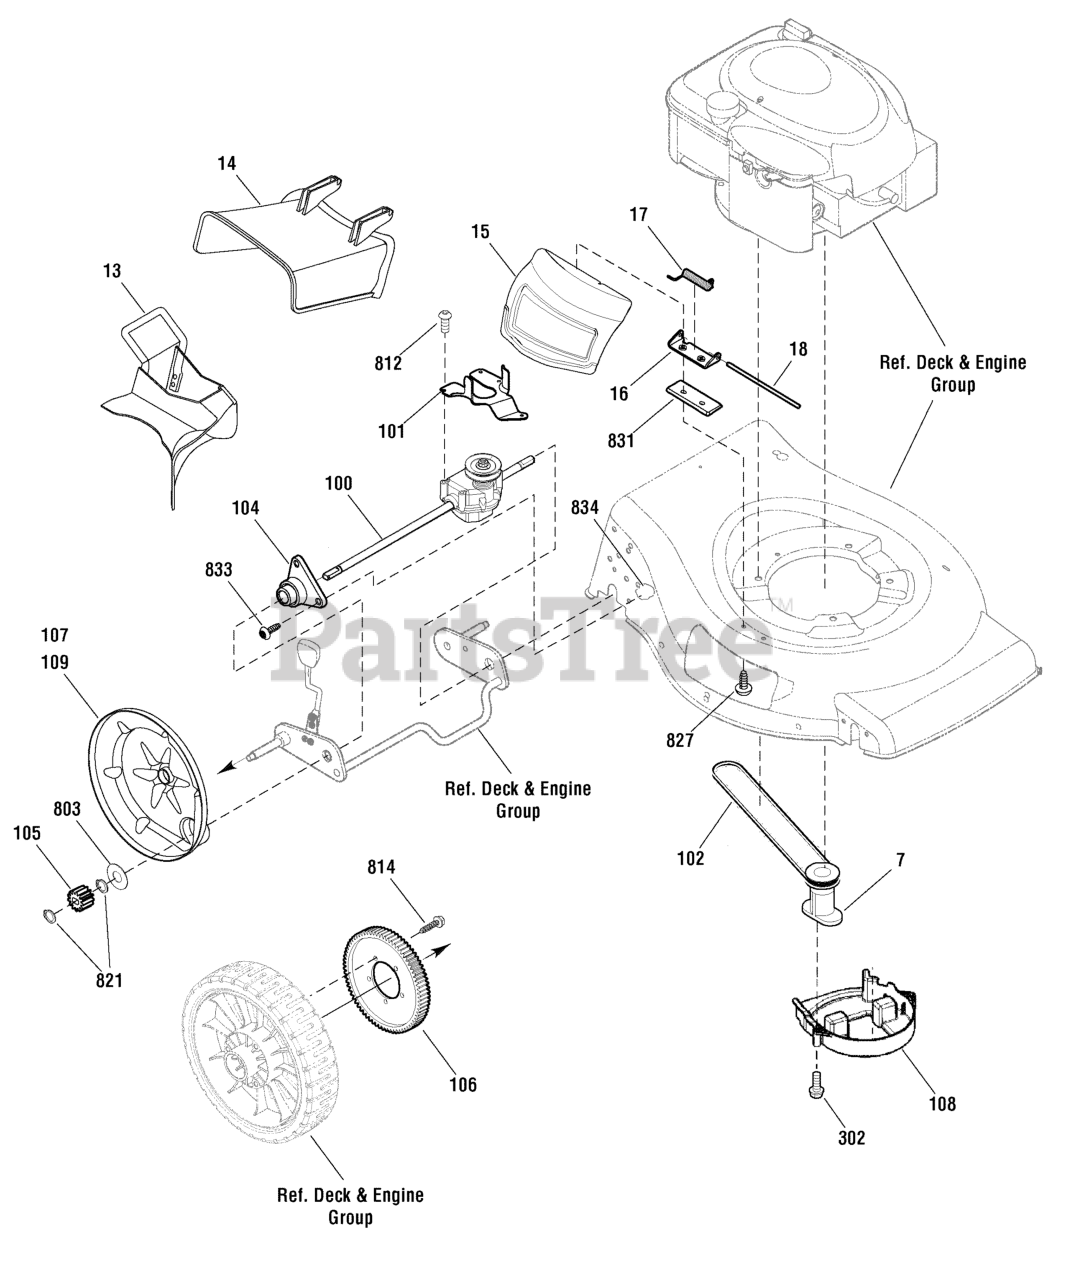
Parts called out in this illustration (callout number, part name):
7	BLADE ADAPTER ASSEMBLY
13	MULCH PLUG
14	CHUTE DEFLECTOR
15	MULCH COVER
16	BRACKET, Chute Deflector
17	SPRING, Chute Deflector
18	ROD, Chute Deflector
100	TRANSMISSION
101	BELT GUIDE, Transmission
104	SLEEVE ASSEMBLY, Rear Axle
105	GEAR, Pinion
106	GEAR, Drive
107	DUST COVER, RH
108	BELT GUIDE
109	DUST COVER, LH
302	SCREW, Pan Head, Taptite, 1/4-15 x 5/8
803	WASHER, Thrust
812	SCREW, #10 x 1
814	SCREW, 1/4-15 x 3/4
821	RING, External Retaining
827	SCREW, 1/4-20 x 1/2
833	SCREW, Torx, 1/4-20 x 5/8
834	NUT, Flange Lock, 1/4-20
